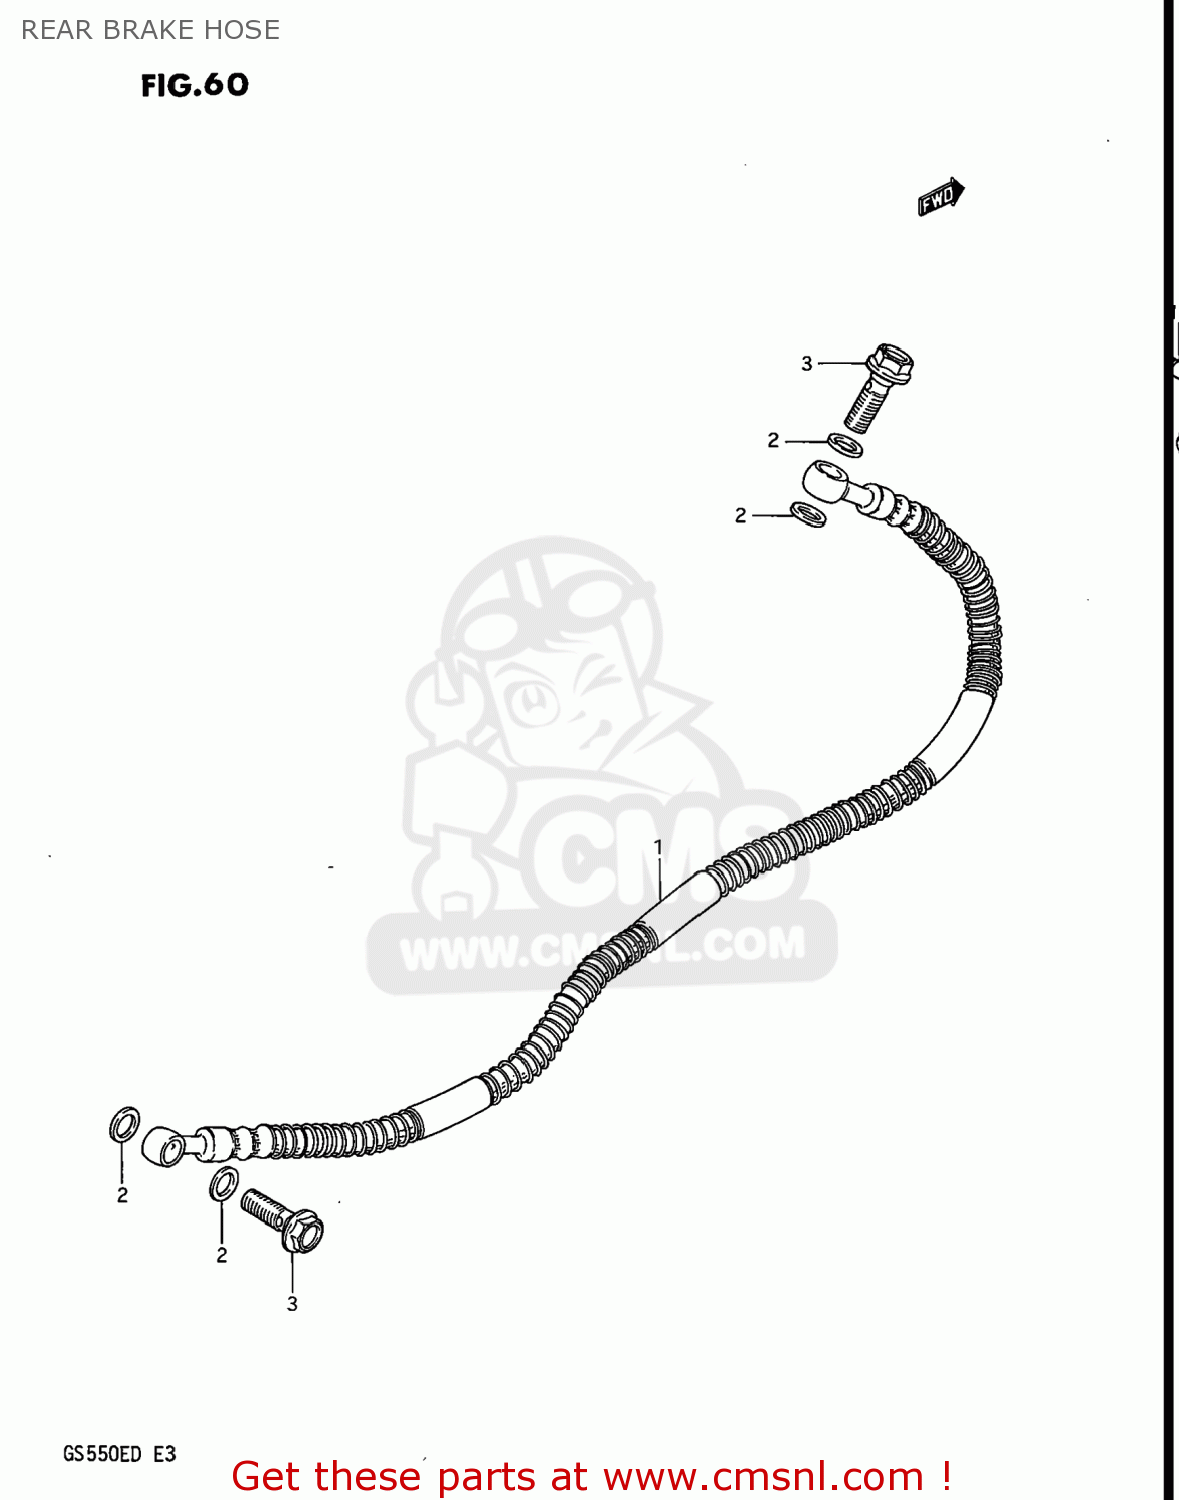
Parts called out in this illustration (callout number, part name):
1	HOSE,REAR BRAKE
2	WASHER
3	BOLT UNION
